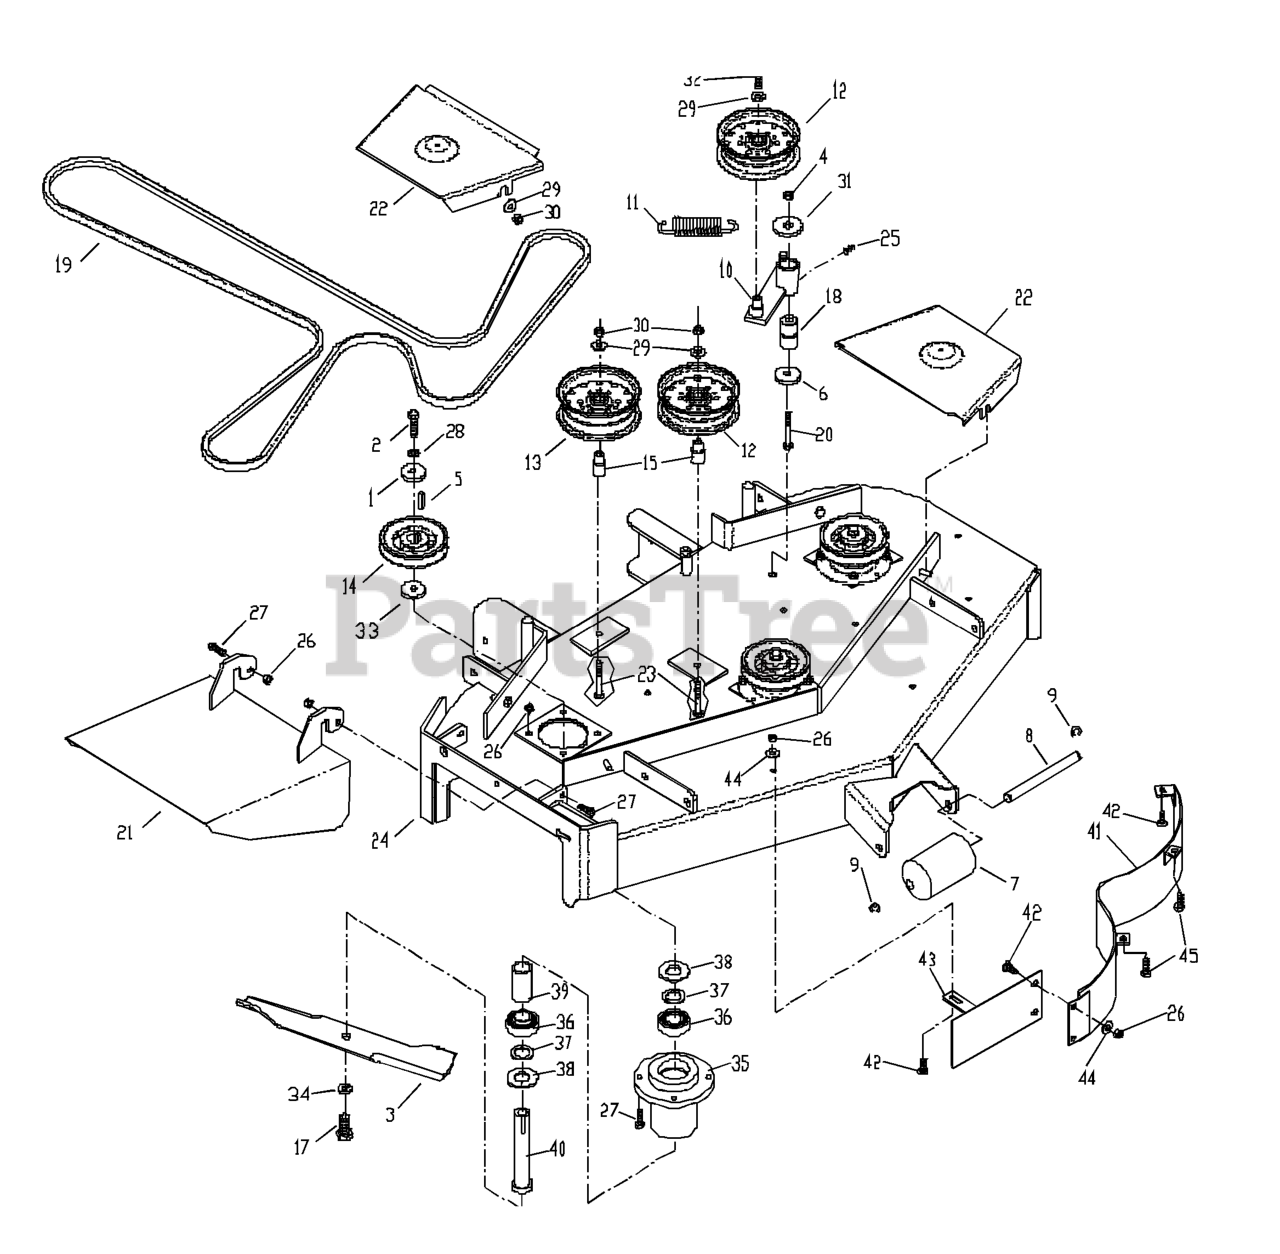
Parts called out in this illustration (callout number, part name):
1	SPINDLE WASHER
2	HCS 7/16F X 1 1/2
3	BLADE OEM, 14-7/8
4	NUT 1/2-13 HEX NYLOC ZD
5	KEY 1/4 SQ X 1 1/8
6	WASHER, SUPPORT
9	E-RING 1/2 (2 2)
12	IDLER PULLEY
13	IDLER PULLEY (TALL)
15	IDLER BUSHING
16	HOUSING ASM.
17	HCS 5/8F X 1 1/4
18	PIVOT BUSHING
19	BELT
20	HCS 1/2C X 3 1/4
21	DISCHARGE CHUTE 42"
22	BELT SHIELD
23	HCS 3/8C X 2 1/2
24	DECK W/DECALS
25	ZERK
26	NUT 5/16C CENTERLOCK
27	HCS 5/16C X 1
28	WASHER 7/16 LOCK
29	WASHER 3/8 FLAT
30	NUT 3/8C CENTERBLOCK
31	WASHER 1/2 FLAT
32	4CS 3/8C X 1 SERRATED HEAD
33	MACHINERY BUSHING 10 GA.
34	LOCKWASHER 5/8
35	HOUSING, DIE CAST
36	BEARING
37	BUSHING.MACHINE.18.GAUGE
38	MACHINERY BUSHING 10 GA.
41	MAIN BAFFLE
42	CARRIAGE BOLT 5/16C X 5/8"
43	CENTER BAFFLE
44	WASHER 5/16 FLAT
45	HCS 5/16C X 3/4
